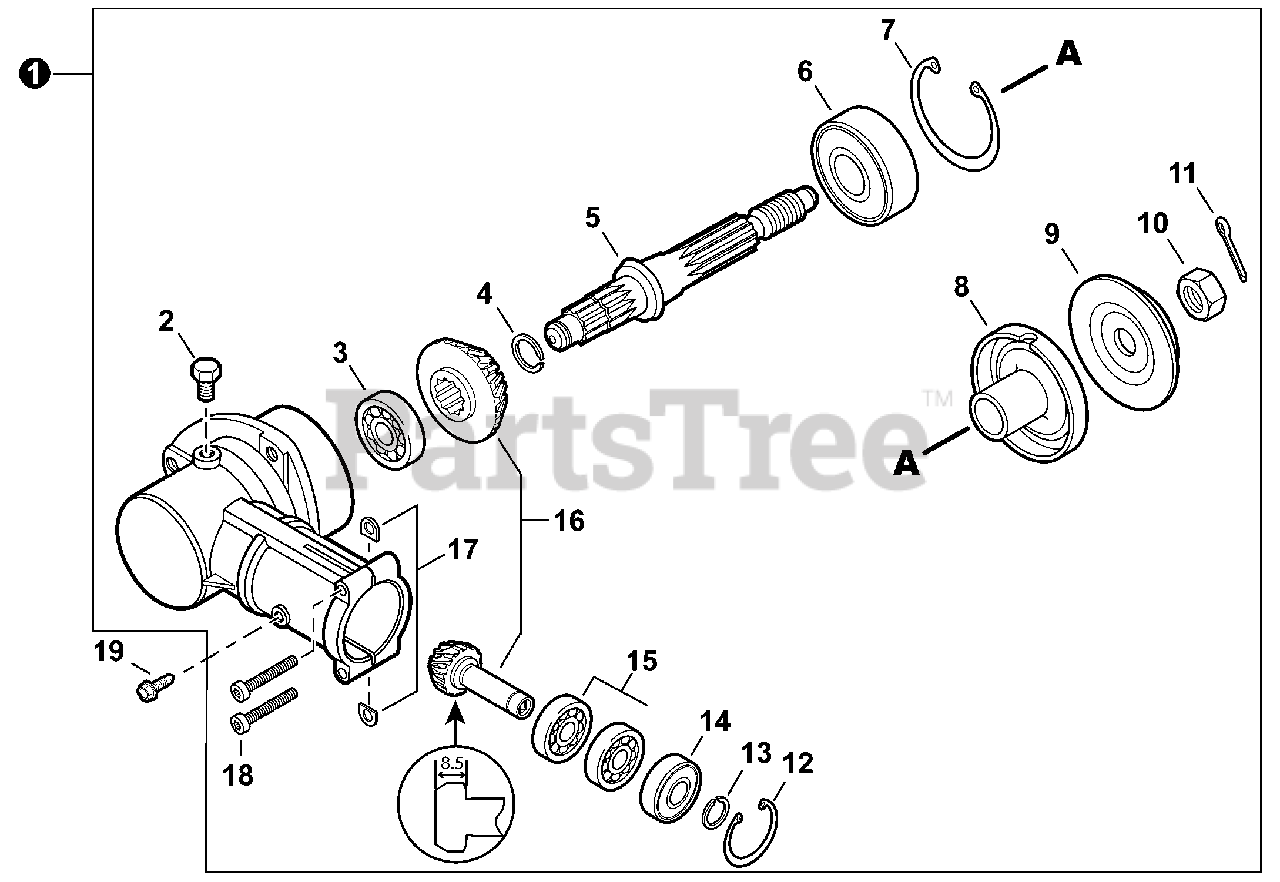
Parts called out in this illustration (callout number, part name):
1	GEAR CASE ASSY
2	BOLT M8×8
3	BEARING, BALL 629
4	RING, SNAP 12
5	SHAFT, GEAR
6	BEARING, BALL 6302
7	RING, SNAP 42
8	PLATE, ADAPTOR - UPPER
9	PLATE, ADAPTOR - LOWER
10	NUT 10×1.25 LH
11	PIN, COTTER 2×22
12	RING, SNAP 22
13	RING, SNAP 10
14	BEARING, BALL 6900-Z
15	BEARING, BALL 6900
16	GEAR SET
17	D-WASHER
18	BOLT, TORX 5×25
19	BOLT, 5 SELF DRILLING
